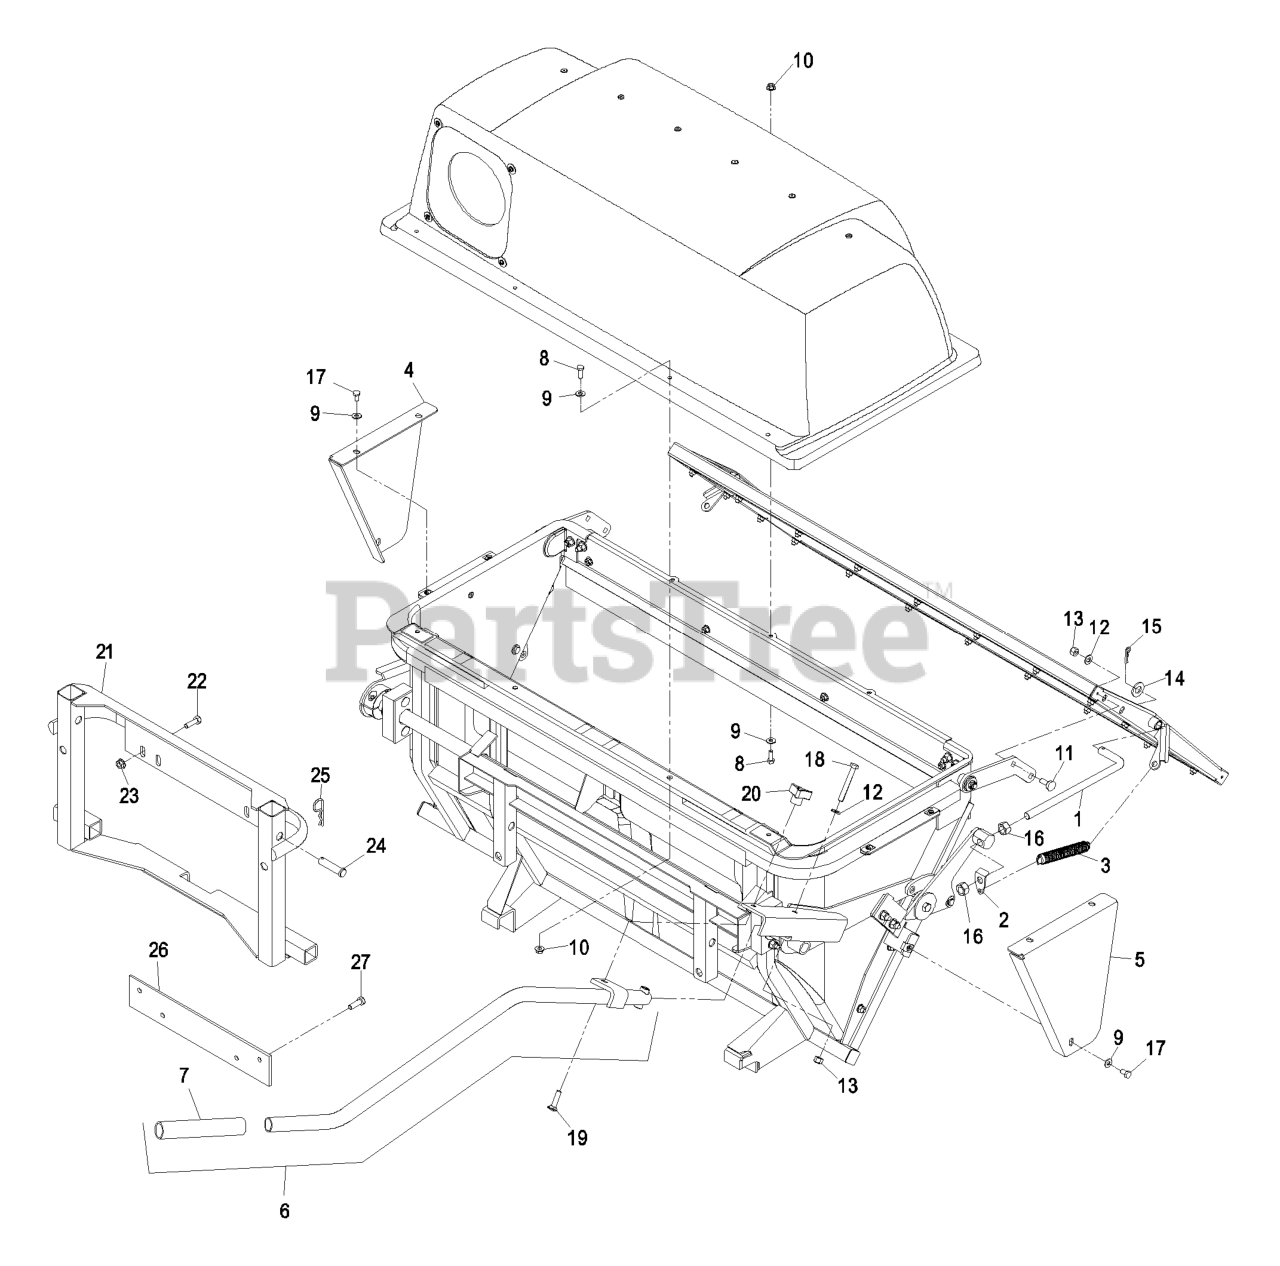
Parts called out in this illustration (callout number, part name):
1	LINK-DOOR
2	ANCHOR-SPRING
6	HANDLE ASM
7	GRIP-BAR, HANDLE
8	SCREW-HH
9	WASHER-FLAT
11	SCREW-CARR
12	WASHER-PLAIN
13	NUT-LOCK, NI
14	WASHER-FLAT
15	PIN-COTTER
16	NUT-HEX
17	SCREW-HH
18	SCREW-HH
19	Bolt-Carriage 5/16-18 X 1 1/4
20	KNOB-3 PRONG
21	MOUNT-BAGGER
22	SCREW-HH
24	PIN-CLEVIS
25	PIN-COTTER
26	SPACER,COUNTERWEIGH
27	SCREW-HH
